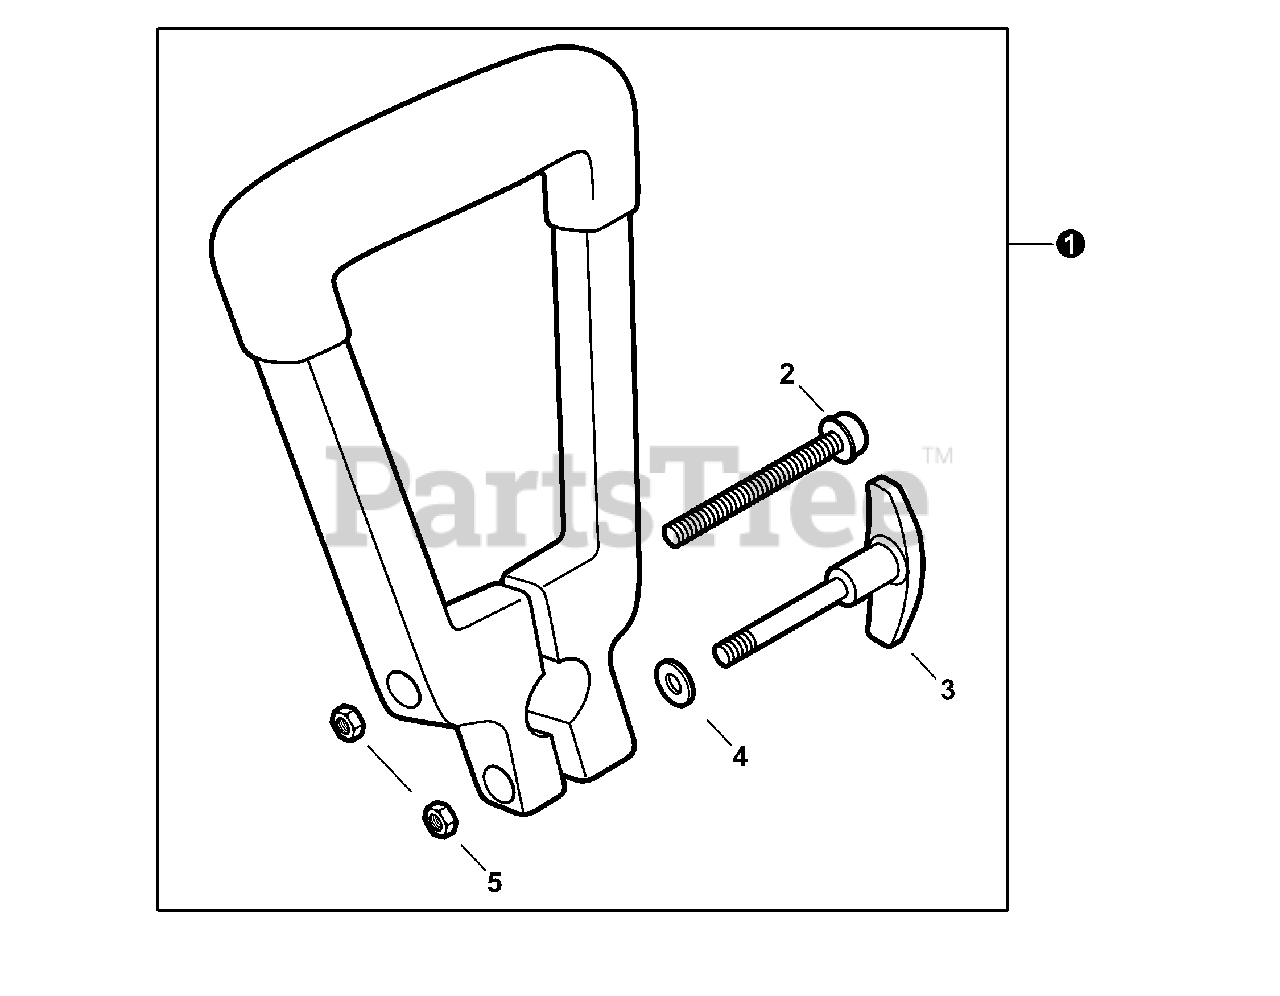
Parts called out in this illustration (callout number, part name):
1	HANDLE ASSY
2	SCREW 6
3	KNOB, SCREW
4	WASHER 6
5	NUT, HEX M6
